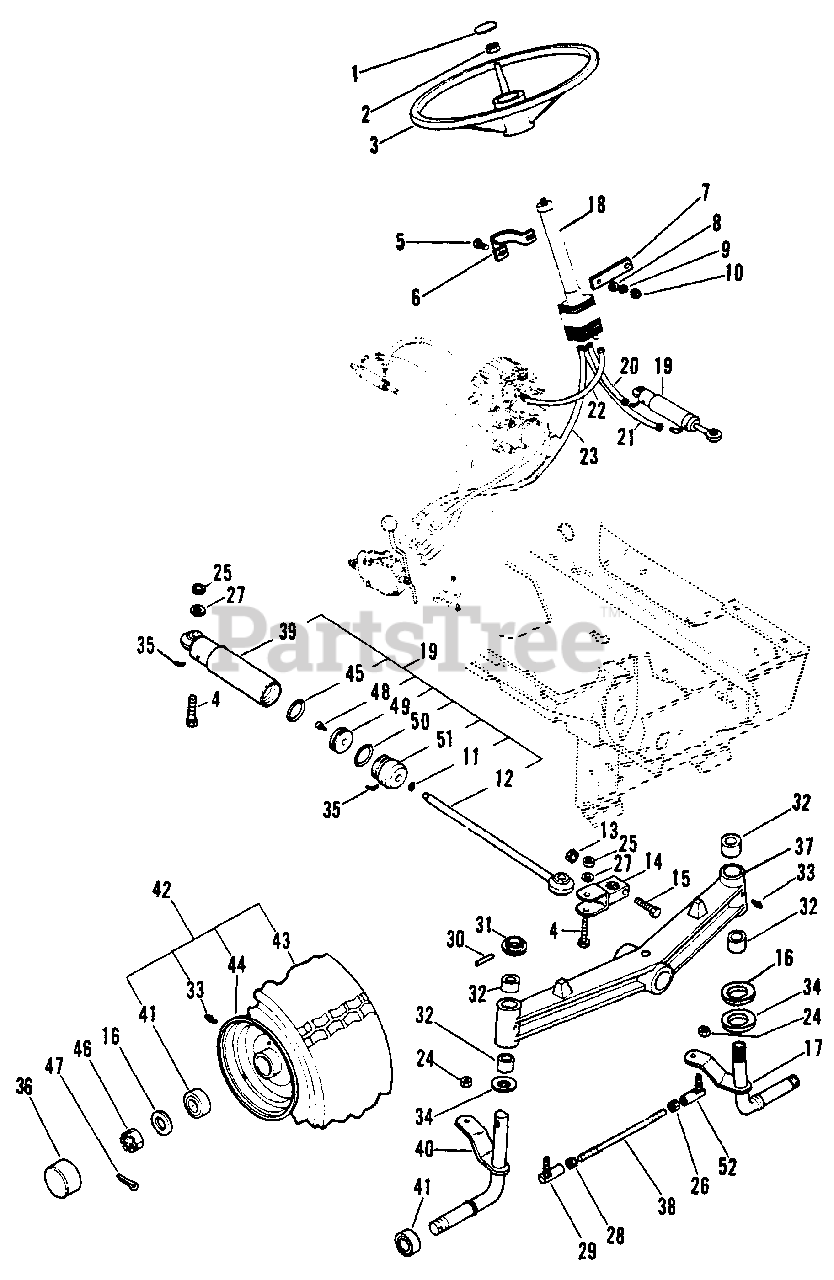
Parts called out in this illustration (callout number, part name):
1	Cap, Lens
2	Nut, Hex Jam Lock 5/8-18
3	Steering Wheel
4	Bolt, Hex 5/16-18 x 2.00
5	Bolt, Carriage 5/16-18 x 1.0
6	Steering Column Clamp
7	Pad
8	Washer, Flat .406 x .812 x .065
9	Washer, Lock 5/16 SP
10	Nut, Hex 5/16-18
11	O-Ring, .625 I.D.
12	Rod
13	Nut, Lock 1/2-13
14	Steering Arm
15	Lock Bolt
16	Washer, 1.000/1.031 x 1.500 x .125
17	Spindle, L.H.
18	Unit, Power Steering
19	Cylinder Assembly Power Steering
20	Hose, Hydraulic
21	Hose, Hydraulic
22	Hose, Hydraulic
23	Hose, Hydraulic
24	Nut, Lock 1/2-20
25	Nut, Lock 5/8-18
26	Nut, Hex Jam L.H. Thd. 1/2-20
27	Washer, Flat .640 x 1.005 x .062
28	Nut, Hex 1/2-20
29	Ball Joint
30	Pin, Spring .250 x 1.750
31	Spindle Cap
32	Bushing, Sleeve 1 x 1-1/8 x 7/8
33	Fitting, Lube 1/4-28
34	Plastic Washer
35	Adaptor, 9/16 to 1/4
36	Front Hub Cap
37	Axle, Front
38	Tie Rod
39	Cylinder
40	R.H. Spindle
41	Radial Bearing 1 I.D. x 2 O.D.
42	Front Tire Assembly
43	Tire, Turf Saver 8 x 6.5
44	Rim Assembly Tire Size 8 x 6.5
45	O-Ring, 1.625 I.D.
46	Nut, Slotted Hex 1-14
47	Pin, Cotter .187 x 1.25
48	Screw, Cap 3/8-24 x 1.0 SH
49	Piston
50	O-Ring, 2.125 I.D.
51	Cap, Rod
52	Joint, Ball
